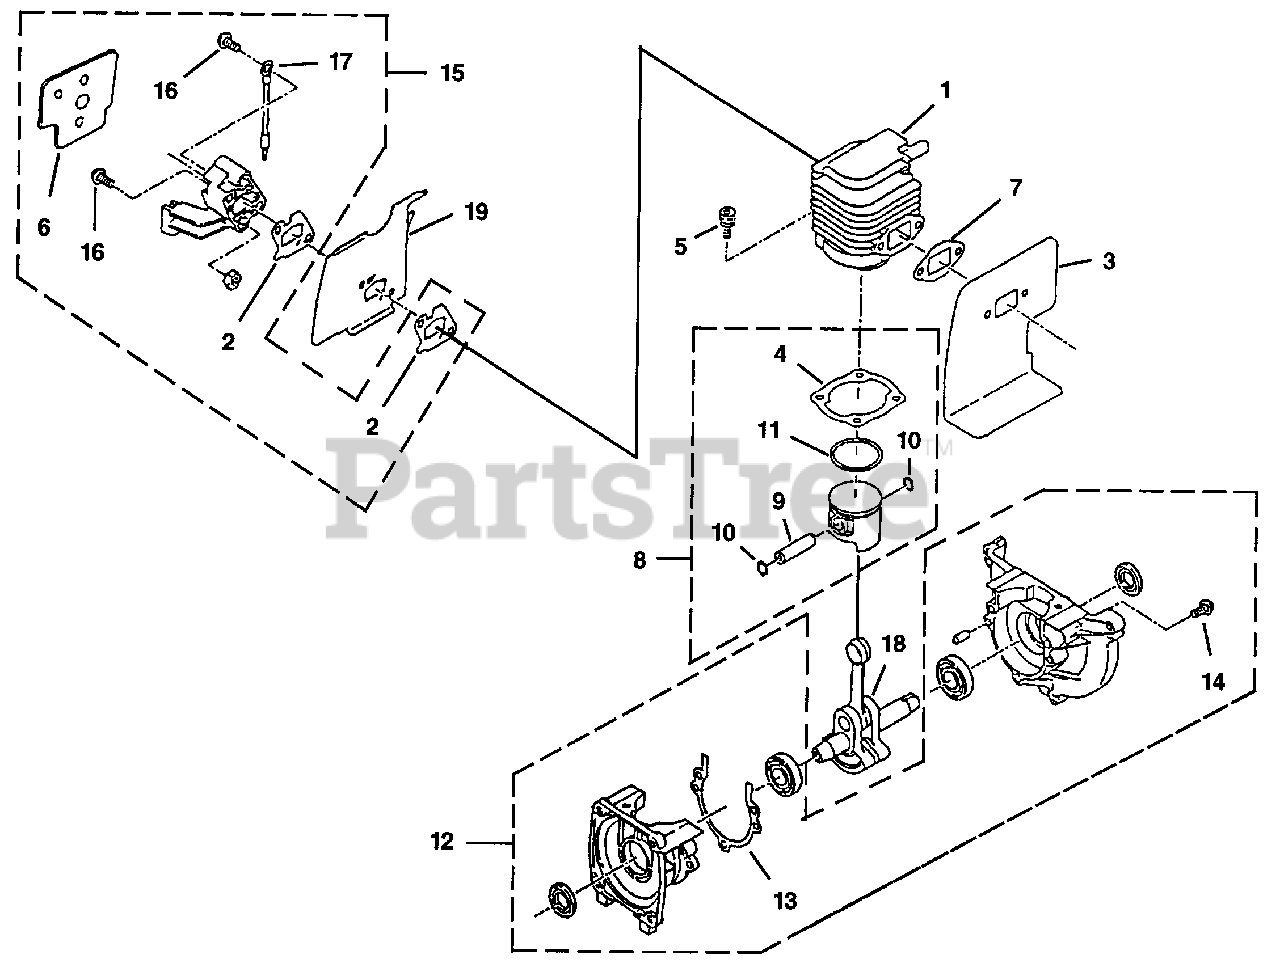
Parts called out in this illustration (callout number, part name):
1	CYLINDER ASSEMBLY
2	GASKET-Heat Dam
3	INSULATOR-Muffler
4	GASKET-Cylinder
5	SCREW-Socket HD (M5 x 20 W SW)
6	INSULATOR-Gasket
6	INSULATOR-Carburetor
7	GASKET-Muffler
8	PISTON ASSEMBLY
9	PIN-Piston
10	RING-Retaining
11	RING-Piston
12	CRANKCASE ASSEMBLY
13	GASKET-Crankcase
14	SCREW (M5 x 25)
15	HEAT DAM ASSEMBLY
16	SCREW-Socket Hd (M5 x 25)
17	WIRE-Ground
18	CRANKSHAFT COMPLETE
19	INSULATOR-Carburetor
